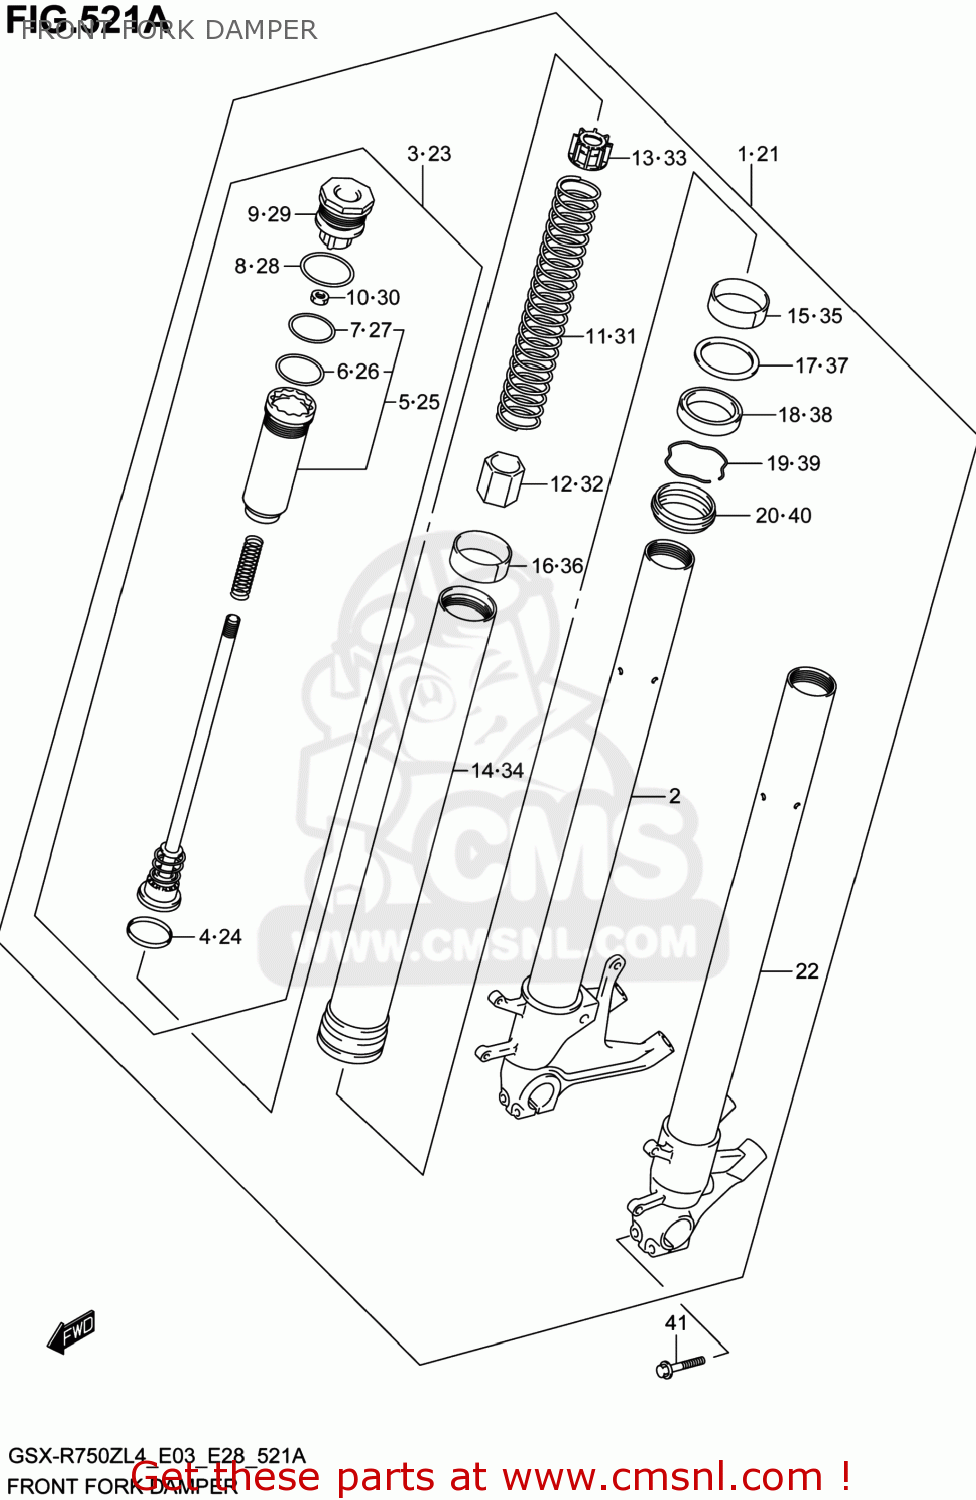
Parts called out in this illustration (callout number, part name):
1	DAMPER ASSY,FR FORK,R
2	TUBE,INNER,R
3	ROD,PISTON
4	RING,PISTON
5	CASE,ROD GUIDE
6	PISTON RING
7	O RING
8	O RING,FORK BOLT
9	BOLT
10	NUT
11	SPRING
12	COLLAR,SPRING
13	COLLAR,SPRING
14	TUBE,OUTER
15	BUSH,GUIDE
16	BUSH,SLIDE
17	SPACER,SEAL
18	SEAL,OIL
19	CIRCLIP,FORK OIL SEAL
20	SEAL,DUST
21	DAMPER ASSY,FR FORK,L
22	TUBE,INNER,L
23	ROD,PISTON
24	RING,PISTON
25	CASE,ROD GUIDE
26	PISTON RING
27	O RING
28	O RING,FORK BOLT
29	BOLT
30	NUT
31	SPRING
32	COLLAR,SPRING
33	COLLAR,SPRING
34	TUBE,OUTER
35	BUSH,GUIDE
36	BUSH,SLIDE
37	SPACER,SEAL
38	SEAL,OIL
39	CIRCLIP,FORK OIL SEAL
40	SEAL,DUST
41	BOLT
